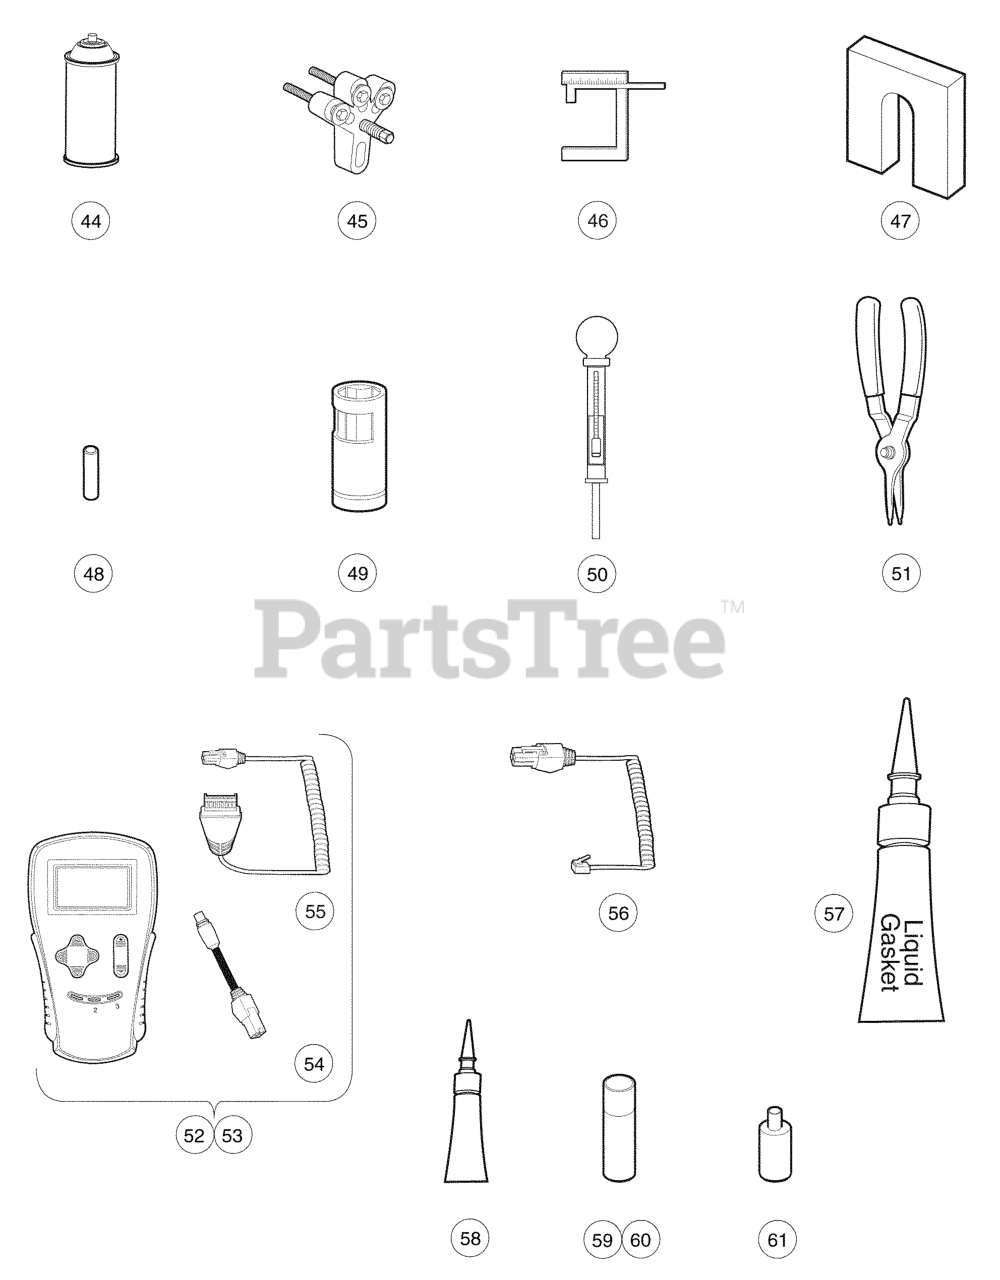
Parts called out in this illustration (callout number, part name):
1	TOOL, ACCEL. PEDAL ADJUSTMENT
2	GUIDE RING ADHESIVE 3 GRAMS
4	BATTERY DISCHARGE UNIT 36/48V
5	BATTERY TERMINAL PROTECT SPRAY
6	BATTERY THERMOMETER
7	BEAR & OIL SEAL REMOVER ASM
8	BEARING DRIVER SET
9	BEARING PULLER
10	BEARING PULLER WEDGE ATTACH.
11	BRAKE ADJUSMENT SOCKET TOOL
12	BRAKE CABLE RELEASE TOOL
13	Brake Pedal Adjustment Tool Kit
14	Brake Pedal Adjustment Tool
15	Brake Pedal Tension Tool
16	CALIBRATION & TEST MODULE
17	CAM INSTALLATION TOOL
18	CHARGER BEZEL TOOL
19	TOOL, REMOVAL, CLUTCH, GAS/DSL
20	C.C. CLUTCH TOOL KIT
21	TOOL, CLUTCH ALIGNMENT
22	TOOL, CLUTCH PULLER
23	CLUTCH DRIVE HUB PULLER
24	DRIVEN CLUTCH CAM PULLER
25	DRIVEN CLUTCH PULLER PLUG
26	DRIVE CLUTCH HOLDER TOOL ASM.
27	PRESS WELDMENT
28	TOOL-STATIONARY PRIMARY
29	TOOL-SPRING COMPRESSION BASE
30	TOOL-SPRING COMPRESSION COLAR
31	TOOL-SPRING COMPRESSION COLAR
32	TOOL-SPIDER PRIMARY
33	COMMUNICATION DISPLAY MODULE
34	COMPRESSION GUAGE AND ADAPTER
35	CONTINUITY TESTER
36	CUTTER, VALVE SEAT, #122
37	CUTTER, VALVE SEAT, #115
38	ADAPTER, T-WRENCH
39	ADAPTER, T-WRENCH
40	Cutter, Valve Seat, 60 Degree (requires item 51)
41	PILOT, 6.6 MM
42	PILOT, 6.62 MM
43	PILOT, 6.65 MM
44	LUBRICANT 11OZ CAN SPRAY
45	FLYWHEEL PULLER KIT
46	GAUGE, CARB FLOAT LEVEL
48	INSERT TOOL, GOVERNOR SHAFT
49	ADJUSTER, HYDRAULIC BRAKE
50	HYDROMETER
51	INERNAL RETAINING RING PLIERS
52	KIT, IQDM, USER, SERIES II
53	KIT, IQDM, OEM, SERIES II
54	ADAPTER, 1307 CABLE
55	CABLE, IQDM, SERIES II
56	CABLE, IQDM
57	SEALANT
58	LUBRICANT, MOLY-TEFLON,4 OZ TU
59	TOUCH UP PAINT BEIGE
59	TOUCH UP PAINT, BLACK
59	TOUCH UP PAINT, BURGUNDY
59	TOUCH UP PAINT, CLASSIC BLUE
59	TOUCH UP PAINT, DARK GRAY
59	TOUCH UP PAINT, DARK GREEN
59	TOUCH UP PAINT, GRAY
59	TOUCH UP PAINT, RED
59	TOUCH UP PAINT, ROYAL BLUE
59	TOUCH UP PAINT, WHITE
60	PAINT, GRAY - SPRAY
61	PAINT PEN, UNDERBODY, BLACK
62	KIT, PISTON RING COMPRESSOR
63	PISTON RING PLIER
64	SPECIAL-USE PULLER SET
65	EXTERNAL SNAP RING PLIERS
66	INTERNAL SNAP RING PLIER 9O
67	SAFETY FIRST CARD
68	SEAL PULLER
69	WRENCH, SPANNER
70	Steering Column Bearing Press Tool
71	TOOL-STEERING RETAINING RING
72	PULLER, STEERING WHEEL
73	TACHOMETER GAS/DIESEL
74	TACHOMETER DIESEL ADAPTOR
75	TRANS-AXLE, AXLE SEAL TOOL
76	Transaxle Pinion Seal Tool
77	Transmission Tool Kit
82	VALVE CLEAR ADJ SCREW HOLDER
83	DRIVER, VALVE GUIDE, 6.6. MM
84	VALVE GUIDE REAMER
85	REAMER-VALVE GUIDE
86	VALVE SEAT CUTTER GUIDE
87	VALVE SEAT CUTTER "T" WRENCH
88	VALVE SEAT CUTTER 45 DEG 32 MM
89	CUTTER INTAKE VALVE ST 45/30
90	VALVE SPRING CMPR & ADAPTER
91	METER, WAVETEK VOLT-OHM
92	S/G TENSIONING TOOL
